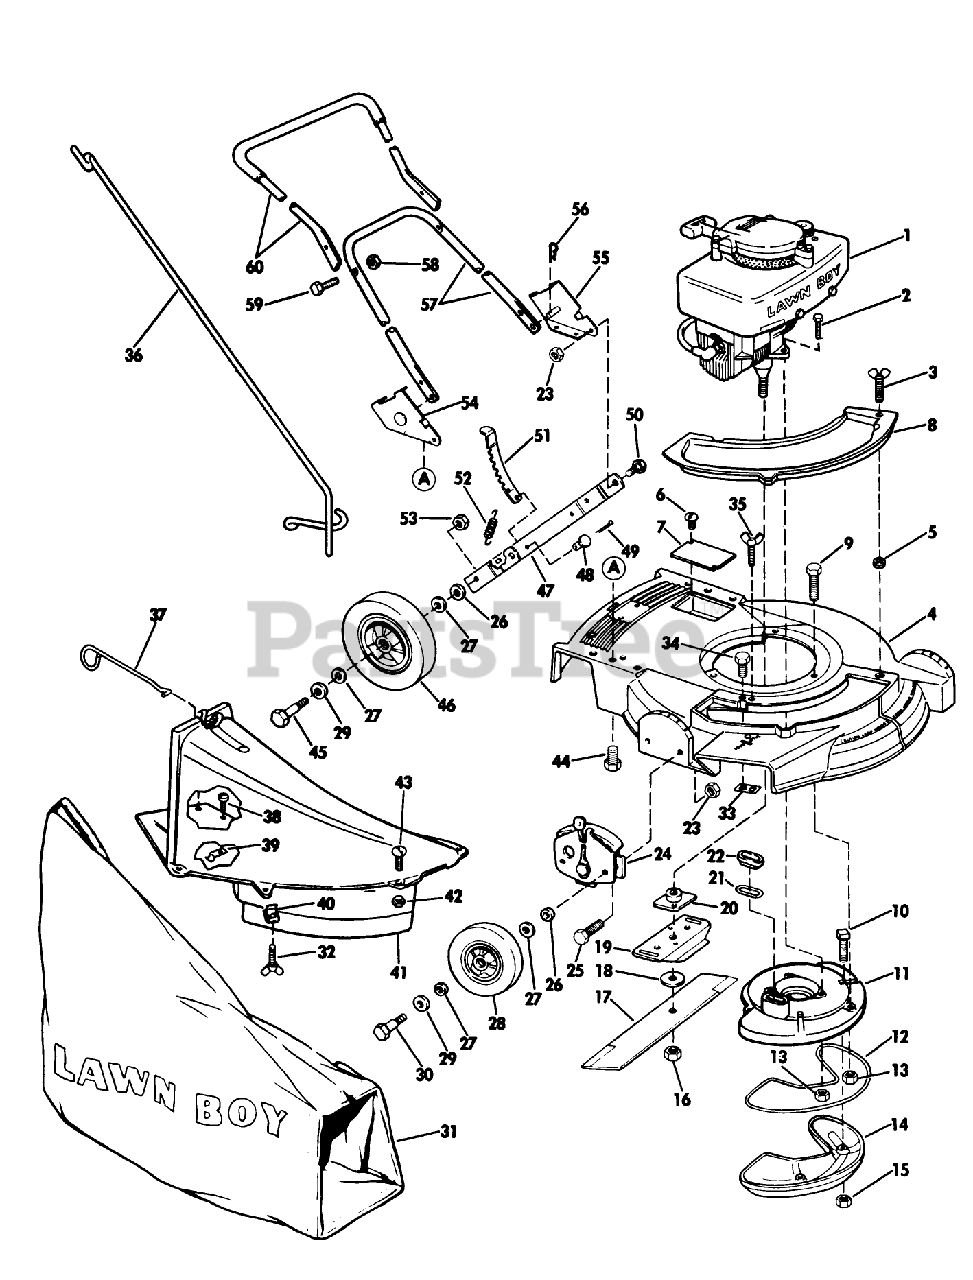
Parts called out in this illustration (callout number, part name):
1	Engine-Model C-18
15	LOCKNUT E
16	NUT-BLADE
20	PLATE AND COLLAR ASM
21	GASKET S
26	WASHER WROUGHT
30	BOLT WHEEL
31	89802 LB WHOLE GOODS
40	SPEED NUT ARDEN
41	Chute Skirt Assembly (Includes Hardware)
50	BOLT-SHOULDER
52	SPRING N.A.S
53	LOCKNUT
56	HAIR PIN
57	Handle-Bottom
58	Nut-Handle
